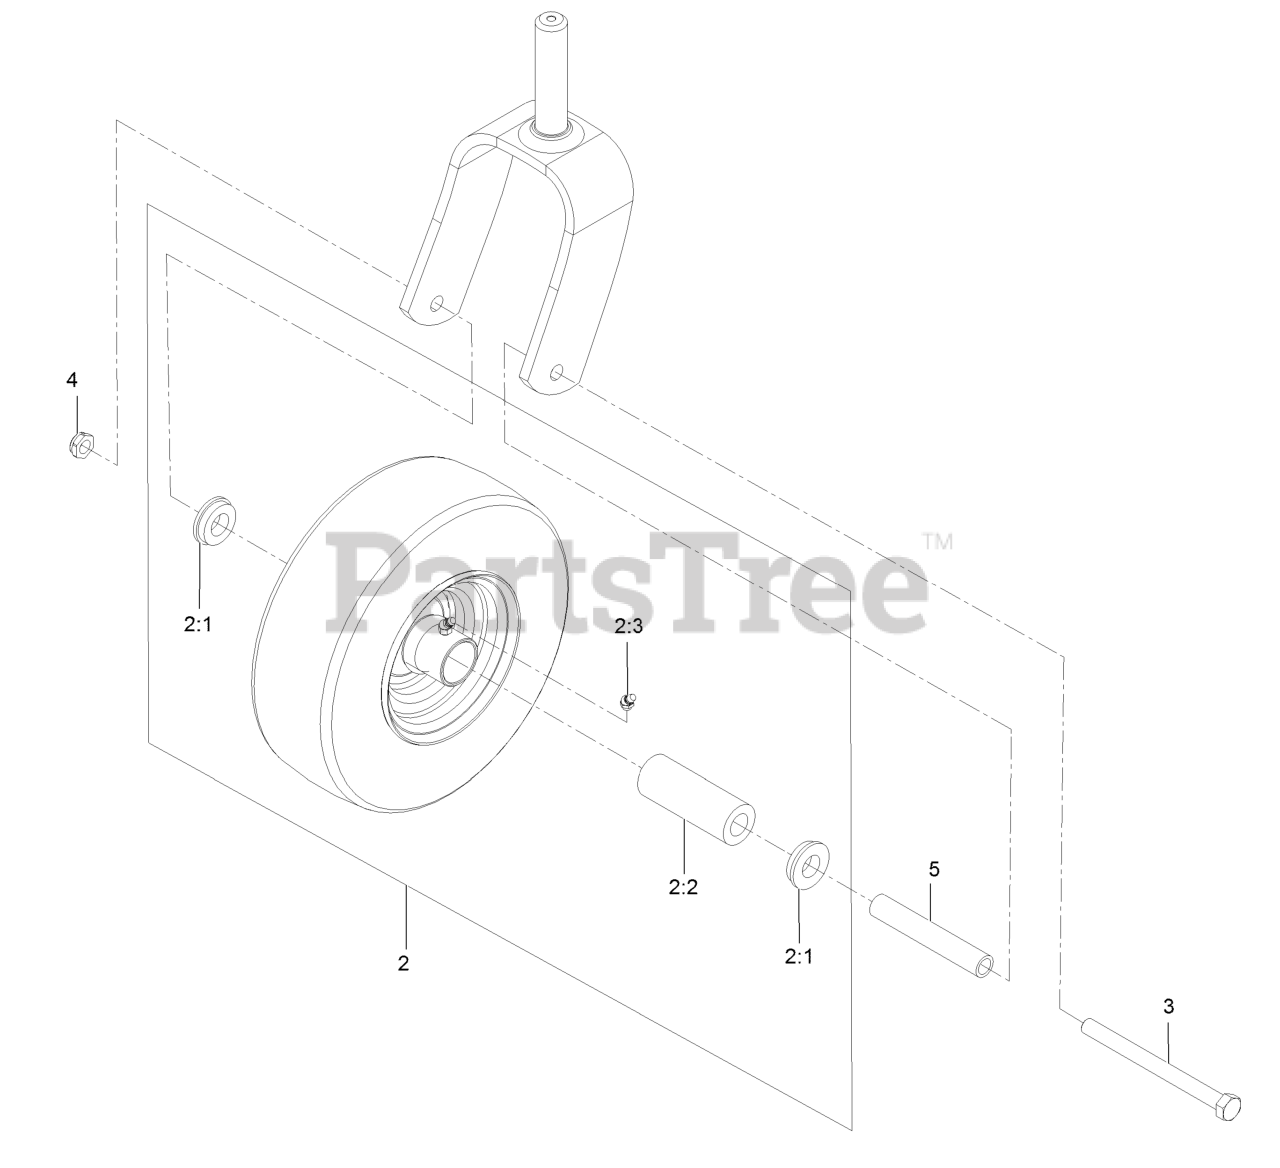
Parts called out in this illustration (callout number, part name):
2	Wheel And Tire ASM
2:1	Bushing-Flanged
2:2	Bearing
2:3	Zerk-45deg 1/4-28
3	Screw-HH 1/2-13 X 6
4	Nut-Nyloc 1/2-13 Thin
